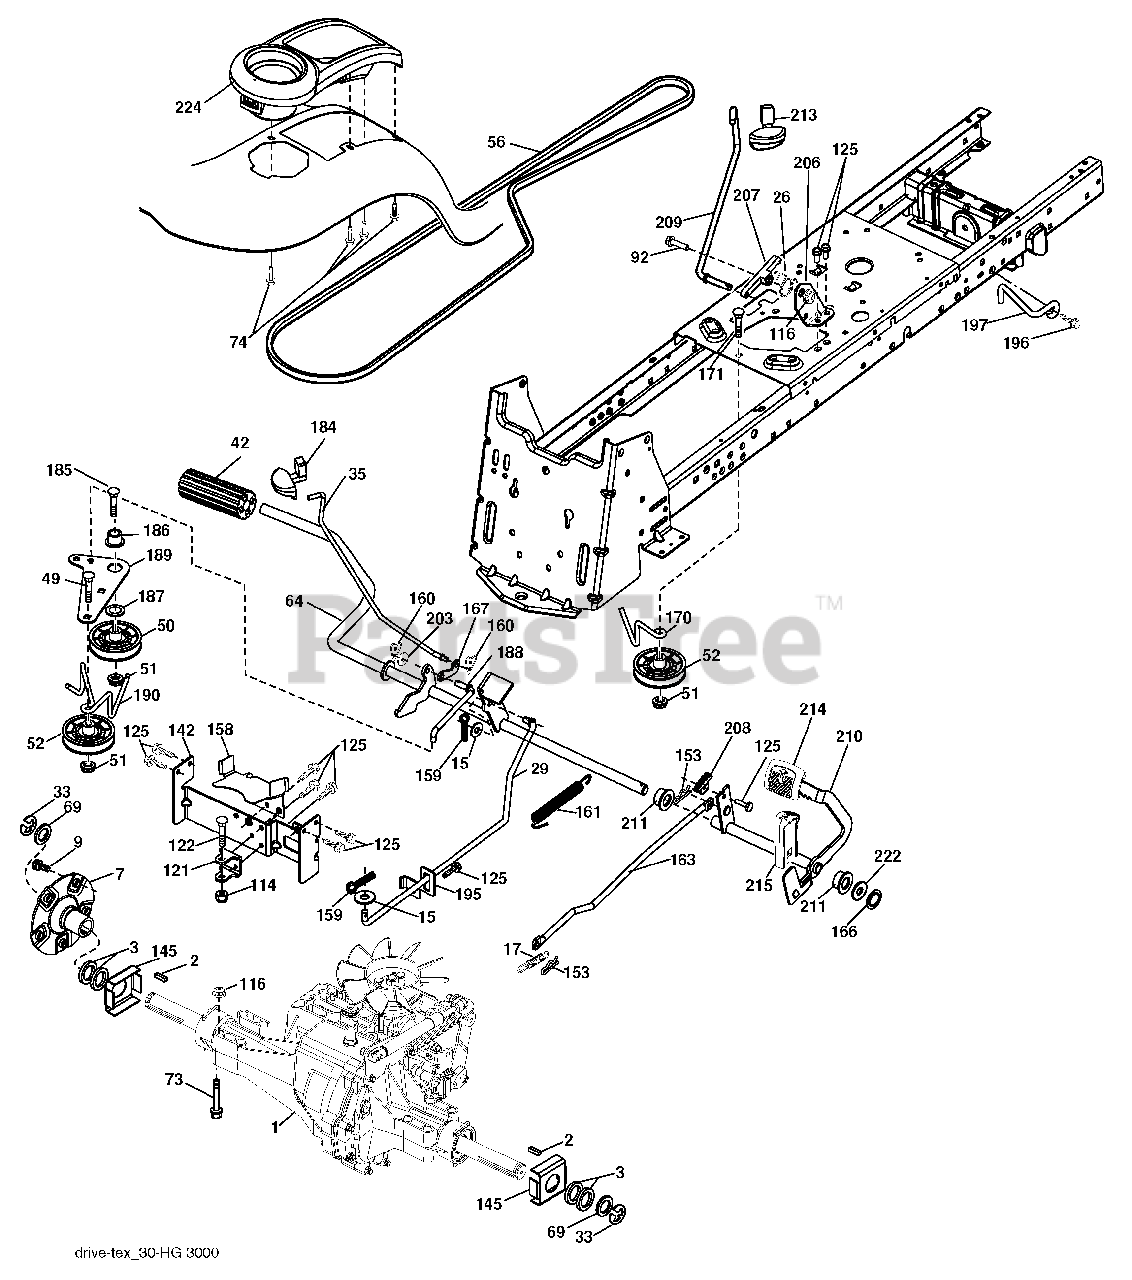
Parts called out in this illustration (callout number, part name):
1	Transaxle, Hydro 347-3000 (See Transaxle Breakdown)
2	Key 1/4 x 2.5
3	Washer Thrust Axle Hardened
7	Hub Asm. Wheel
9	Bolt Hub Wheel
15	Washer 13/32 x 13/16 x 16 Ga.
17	Spring, Brake
26	Spring Return Cruise
29	Rod, Brake
33	Ring E
35	Rod, Brake, Park
42	Cover, Foot Pedal
49	Bolt
50	Pulley Idler Flat
51	Lock Nut 3/8-16
52	Idler V-Groove 910" Offset
56	V-Belt, Drive
64	Shaft Asm. Pedal Brake Control
69	Washer 1-1/32 x 1-5/8 x 16 Ga.
73	Bolt Hex 5/16-18 x 3 Gr. 5
74	Screw 1/4 x 1/2
92	Bolt 5/16-18 x 1/2
114	Nut Lock Hex W/Ins. 5/16-18 unc
116	Nut Lock Hex Flange 5/16-18
121	Bracket Strap Torque
122	Bolt 5/16-18 x 2.50
125	Screw 5/16-18 x 3/4
142	Strap Torque
145	Washer Axle Flange
153	Retainer Spring
158	Keeper Belt T/A
159	Pin Cotter 1/8 x 3/4
160	Retainer Clip
161	Spring, Return, Clutch
163	Rod Pedal Control
166	Nut Push .625
167	Latch Brake Parking
170	Keeper Belt Centerspan
171	Bolt
184	Handle Parking Brake
185	Bolt Rdhd Sqnk 3/8-16 x 2-1/2
186	Spacer Retainer
187	Washer
188	Link Clutch Ground Drive
189	Bellcrank Ground Drive
190	Keeper Bellcrank Ground Drive
195	Retainer Rod Brake
196	Screw 3/8-16 x 1
197	Bracket Clutch Anti-Rotation
203	Washer 11/32 x 11/16 x 16 Ga.
206	Bracket Mount Latch Cruise
207	Latch Control Cruise
208	Gear Sector Control Cruise
209	Rod Control Cruise
210	Rocker Asm. Pedal Control
211	Bearing Nylon
213	Knob Control Cruise
214	Pedal Forward
215	Pedal Reverse
222	Washer 21/32 x 1-1/4 x 10 Ga.
224	Cover Terminal
